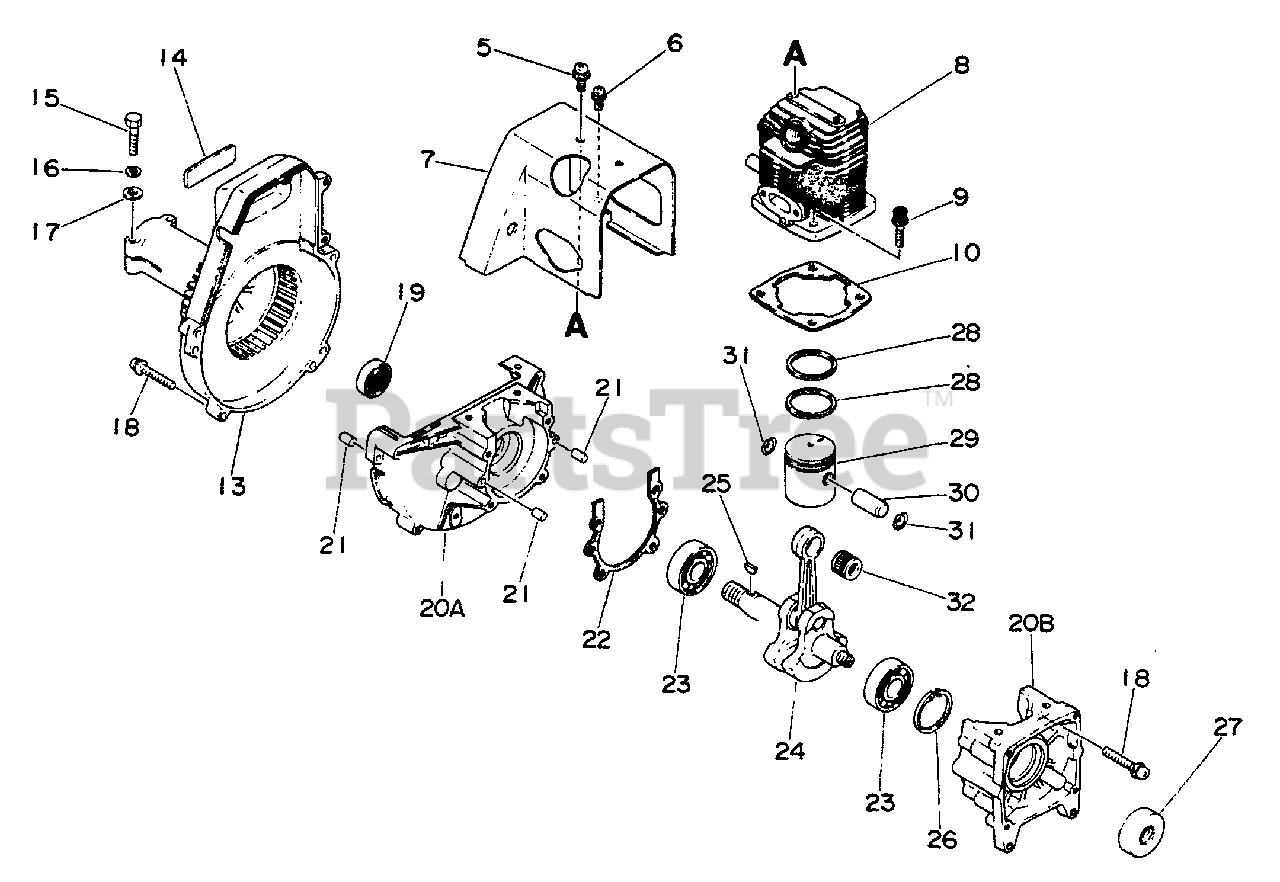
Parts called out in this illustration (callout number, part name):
5	SCREW 5×10
6	SCREW 4×10
7	COVER, ENGINE
8	CYLINDER
9	BOLT 5×20
10	GASKET, CYLINDER
13	CASE, FAN
14	LABEL - MODEL 400AE
15	BOLT - 5×25
16	WASHER, SPRING 5
17	WASHER, FLAT 5.5×10×0.8
18	SCREW 5×30
19	SEAL, OIL
20	CRANKCASE KIT
20A	CRANKCASE KIT
20B	CRANKCASE KIT
21	PIN, LOCATING 5×10
22	GASKET, CRANKCASE
23	BEARING, BALL 6202
24	CRANKSHAFT ASSY
25	KEY, WOODRUFF
26	RING, SNAP 35
27	SEAL, OIL 18
28	RING, PISTON
29	PISTON
30	PIN, PISTON
31	RING, SNAP 8
32	BEARING, NEEDLE
